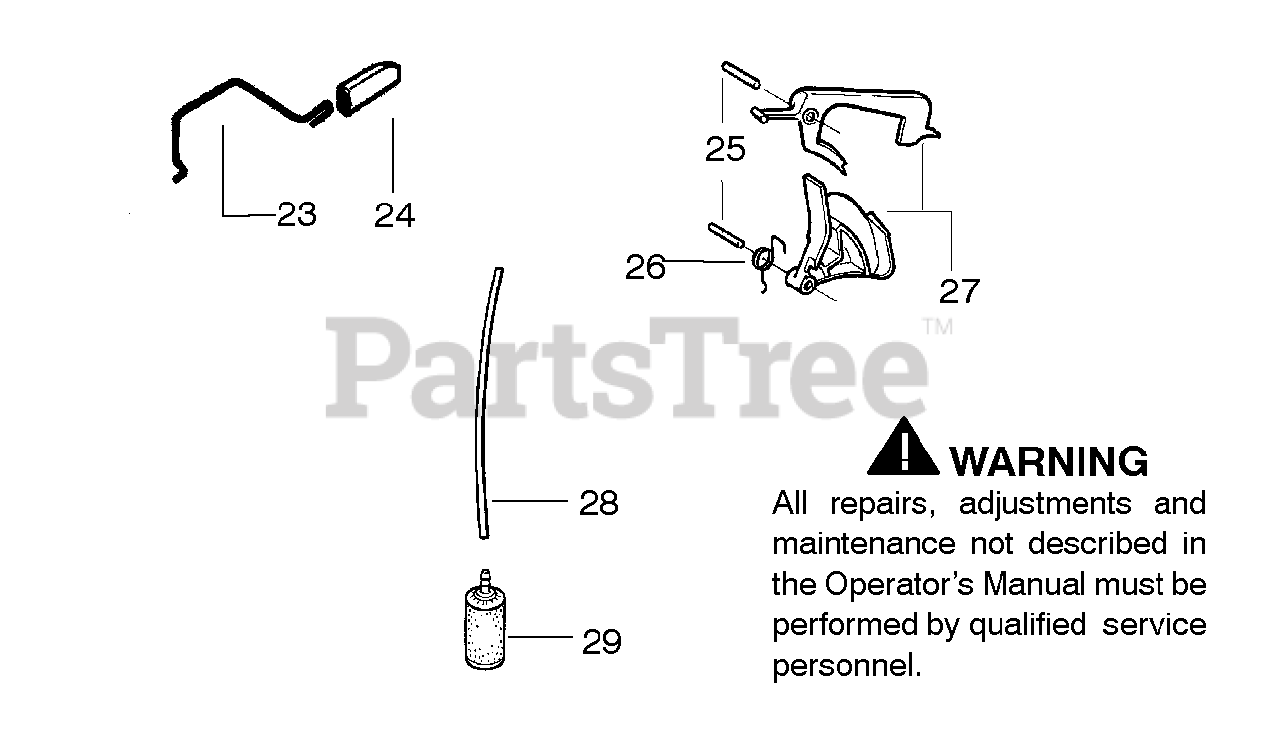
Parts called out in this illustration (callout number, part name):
23	Wire - Throttle
24	Cap - Wire
27	Kit - Throttle Trigger
28	Kit - Fuel line
29	Assy.- Fuel Pickup
